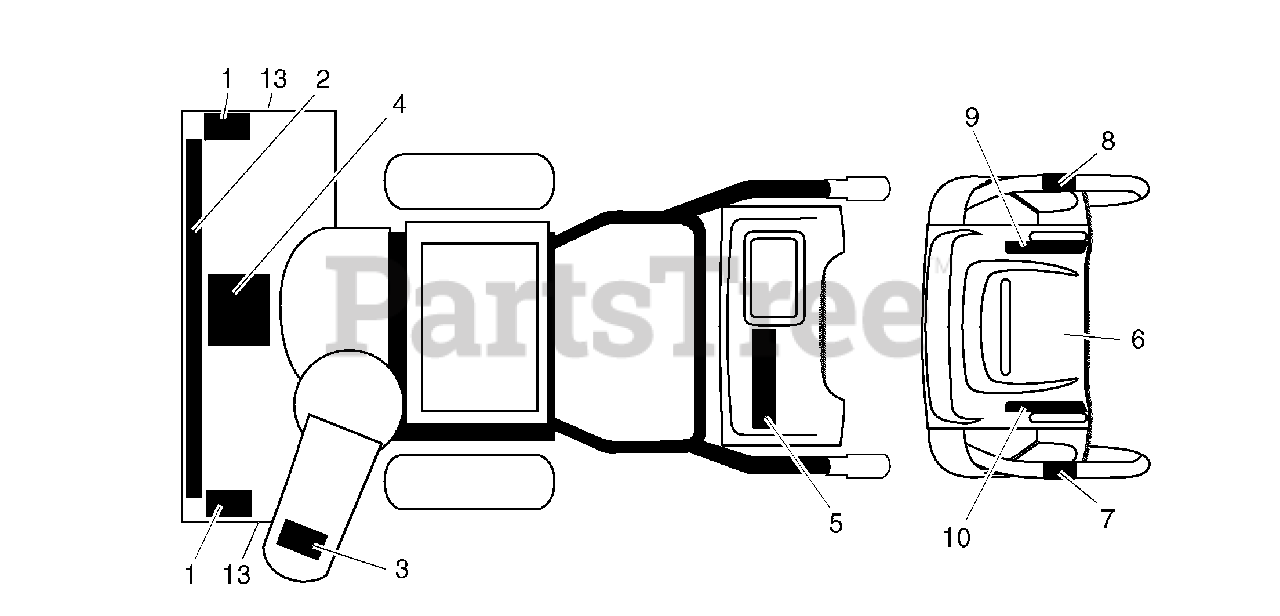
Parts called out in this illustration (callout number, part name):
1	Decal, Danger
2	Decal, Husqvarna
3	Decal, Danger, Deflector
4	Decal, Danger
5	Decal, Husqvarna, 8527SBE
6	Decal, Instruction
7	Decal, Traction Lever
8	Decal, Auger Lever
9	Decal, Speed Control
10	Decal, Remote Deflector
13	Decal, Husqvarna, Crown
